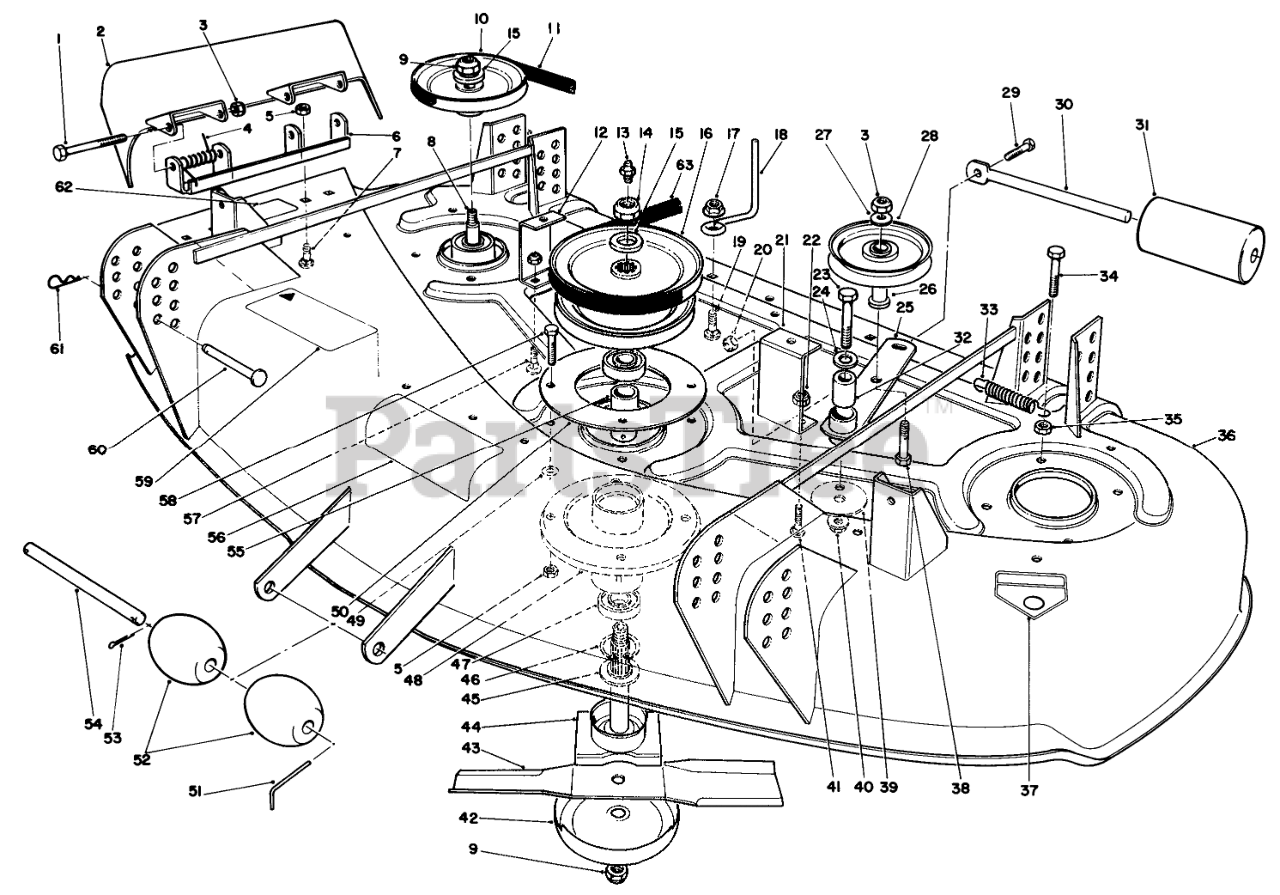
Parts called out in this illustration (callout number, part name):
1	SCREW-HH
2	Deflector-Grass
3	NUT-HEX
4	SPRING
5	NUT-LOCK, CONE
6	PIVOT BRKT WA R/B
7	SCREW-CARR
8	SPDL/BLD RET.WA
9	NUT-LOCK NI
10	DECK PULLEY
11	V-BELT
12	Bracket-Cover RH
13	FITTING-GREASE
14	NUT-LOCK, NI
15	WASHER
16	PULLEY WA
17	NUT-HF
18	ROD-BELT
19	BOLT-CARR
20	NUT-LOCK, NI
21	Bracket-Cover
22	NUT-LOCK, NI
23	SCREW-HH
24	WASHER-FLAT
25	Idler Arm
26	BUSHING-PULLEY
27	WASHER-FLAT
28	PULLEY-IDLER
29	SCREW-HH
30	ROD-ROLLER
31	ROLLER-DECK
32	SLEEVE
33	Spring-Extension
34	SCREW-HH
35	NUT-JAM
36	Housing
37	DECAL-DANGER
38	SCREW-HH
39	WASHER-END
40	NUT-HF
41	SCREW-CARR
42	Cup
43	Blade
44	SPDL/BLD RET.WA
45	IDLER SPACER
46	RING-RETAINING
47	BEARING-BALL
48	Spindle
49	WASHER-FLAT
50	DECK RING
51	PIN-SPECIAL
52	ROLLER
53	Pin-Cotter
54	SHAFT-ROLLER
55	BEARING SPACER
56	DECAL
57	BOLT-CARR
58	SCREW-HH
59	CAUTION DECAL
60	PIN-CLEVIS
61	PIN-HAIR
62	DECAL-CAUTION, BLADE
63	V-BELT, DRIVE
